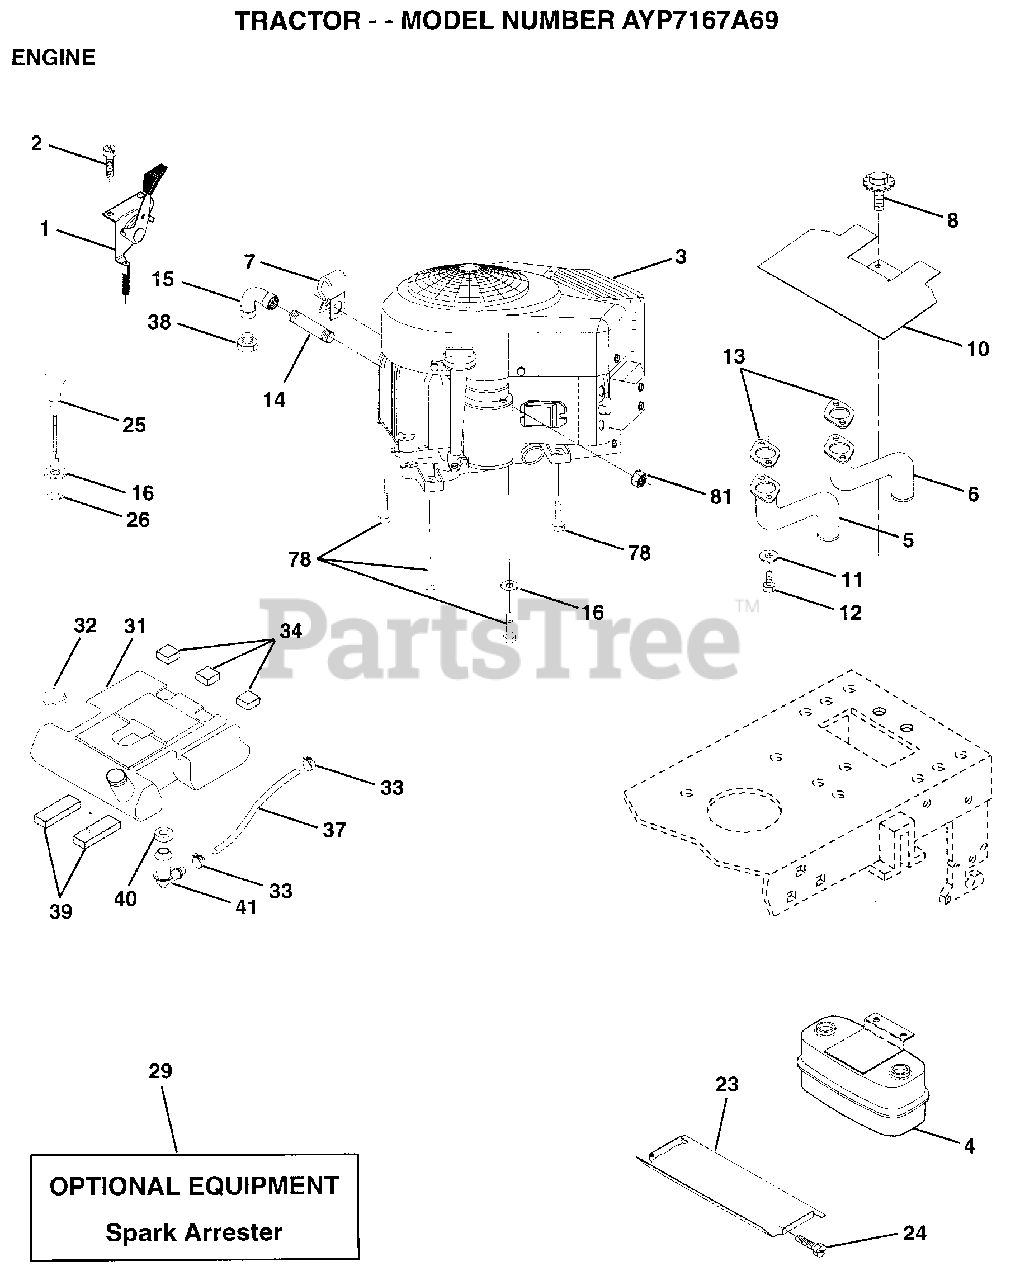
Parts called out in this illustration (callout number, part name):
1	CONTROL THROT. LH
2	SCREW LT
4	MUFFLER.TW.LOTONE
5	TUBE ASSY EXH LH
6	TUBE ASSY EXH RH
7	CLAMP.TUBE.DBL.EN
10	SHIELD.HEAT.
14	PIPE NIPPLE LT
15	ELBOW
16	LOCKWASHER
23	HEAT SHIELD
24	SCREW
25	CONTROL.CHOKE.37
32	CAP ASM FUEL
33	HOSE CLAMP
34	PAD-SPACER LT
35	SCREW
36	WASHER
37	FUEL LINE T
39	PAD IDLER TI
40	BUSHING OUTLET T
41	STEM.TANK.FUEL
78	SCREW
81	NUT
